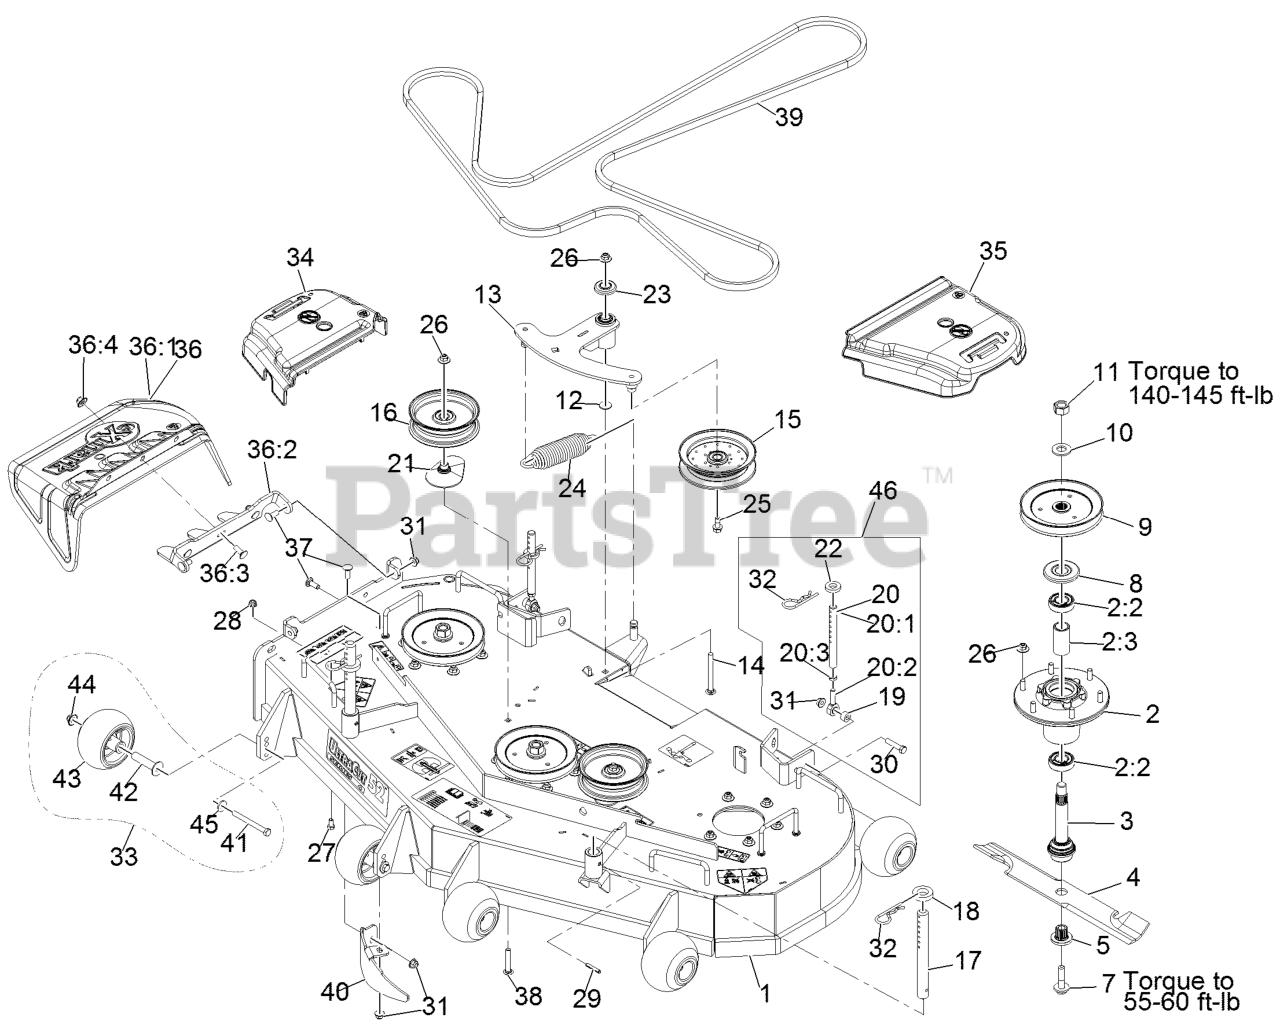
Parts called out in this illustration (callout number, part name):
1	ASM, DECK W/ DECALS, 52"
2	ASM-CUTTER HSG WITH BEARINGS
2:2	BEARING-BALL
2:3	SPACER-BEARING
3	ASM-SPINDLE AND SEAL
5	BUSHING,SPLINED
7	SCREW,SEMS 1/2-20 X 2.19
8	GUARD,BEARING TOP .989
9	SHEAVE,BLADE DRIVE 6.50
11	NUT-HEX
12	WASHER-FLAT
13	ASM, DECK IDLER
14	SCREW-CARR
16	IDLER-PULLEY, FLAT
17	ROD,DECK SUPPORT
18	SPACER-DECK SUPPORT
20:1	LINK,SUPPORT
20:2	BALLJOINT
20:3	NUT-HJ
21	SPACER-PULLEY
23	GUARD-TOP
24	SPRING-EXTENSION
25	SCREW-HFH
26	Nut-Nyloc 3/8-16 Flg
27	SCREW-HH
28	NUT-HF, NI
30	SCREW-HH
31	NUT-HF, NI
32	PIN,HAIR COTTER
33	KIT, ANTI-SCALP ROLLER
34	COVER-BELT, RH
35	COVER-BELT, LH
36	ASM,DISCHARGE CHUTE
36:1	CHUTE,DISCHARGE
36:2	BRACKET,DISCHARGE CHUTE
36:3	SCREW-CARR
36:4	Nut-Nyloc 3/8-16 Flg
37	SCREW-CARR
38	BOLT-CARR, SHORT NECK
39	BELT, DECK DRIVE
40	BAFFLE-DOGLEG, LZ-VT52
41	SCREW-HH 3/8-16 X 3 3/4 GR 8
42	AXLE, ROLLER
43	ROLLER-SCALP, ANTI
44	Nut-Nyloc 3/8-16 Flg
45	WASHER-BELLEVILLE
46	KIT,SUPPORT LINK W/PIN
